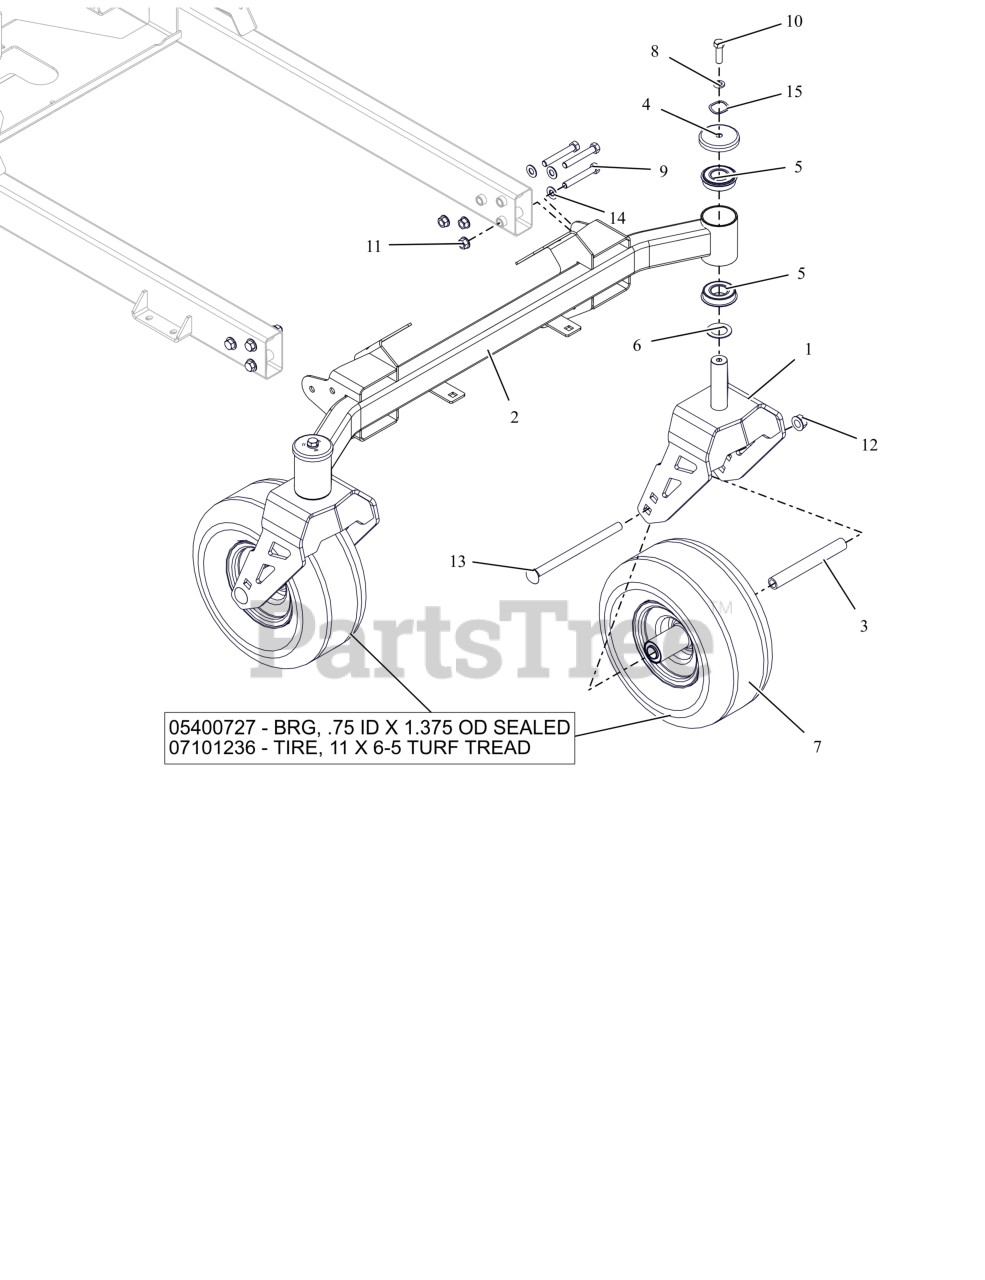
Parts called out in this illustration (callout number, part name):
1	WLDMT, CASTER FORK-XL (ORANGE)
2	WMT-FRONT AXLE-X/XL
3	SPACER, FRONT WHEEL (WIDE 6.0)
4	SHIELD, AXLE BEARING
5	BEARING, BALL -2.000 OD X 1.000 ID X .5625 W/RING
6	WSHR-HRD-THRS 1.007X1.542X.062
7	TIRE/WHEEL ASSY, 11X6-5
7	BRG, .75 ID X 1.375 OD SEALED
7	TIRE, 11X6-5 TURF TREAD
8	WSHR,LK-REG .375X.094 ZCC
9	BLT, HEX .38-16X2.50 G8 ZCC
10	BLT, HEX .38-16X1.25 G5 ZCC
11	NUT-LK-TOP-FLG .375-16 GG ZCC
12	NUT-LK-TOP-FLG .500-13 GF ZCC
13	BLT, RHSN .50-13X7.50 G5 ZCC
14	WSHR,FLT-HRD.406X.812X.055 MZC
15	WSHR-WAVE 1.0X1.25X.028 .145FH
